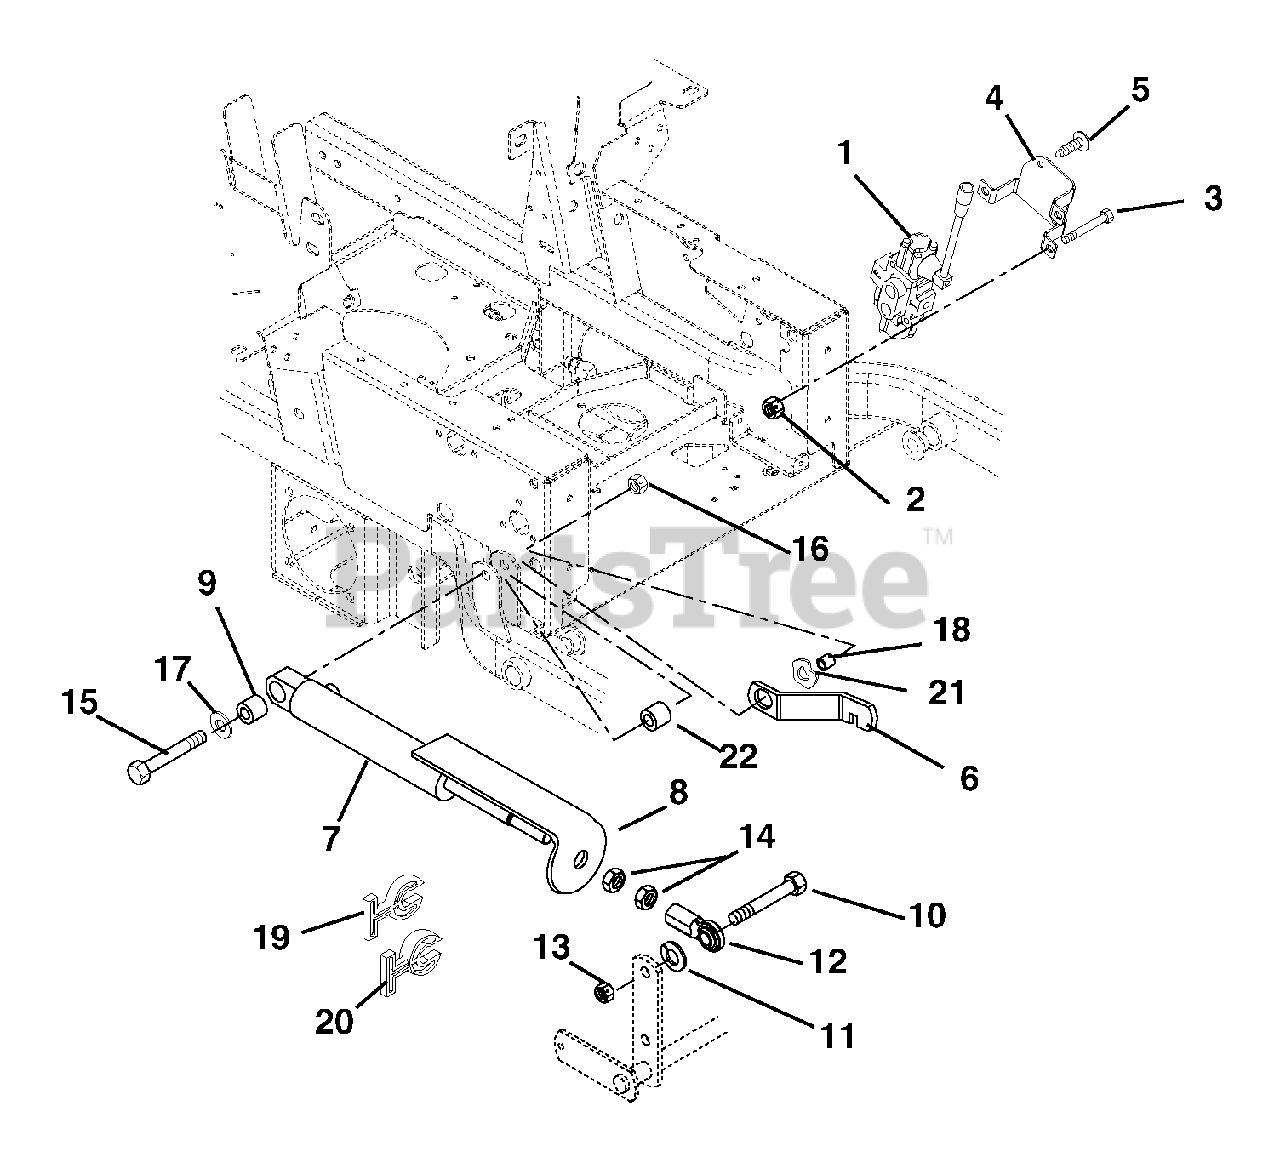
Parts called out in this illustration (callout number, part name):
1	Valve, Hydraulic
2	Nut, Locking Top Flange .31-18
3	Bolt, Hex .31-18 x 2.25 Grade 5
4	Valve Mounting Bracket
5	Screw, Tapping .38-16 x .50 Hex Washer Head
7	Cylinder, Hydraulic Lift
8	Strap, Cut Indicator/Guard
9	Bushing .516 x 1.000 x 1.050
10	Bolt, Hex .62-11 x 2.25 Grade 8
11	Washer, Lock .62 x .156
12	Rod End - Female - Right Hand .63
13	Nut, Locking Center .62-11
14	Nut, Jam .625-18
15	Post, Cylinder Stop
16	Nut, Locking Top Flange .50-13
17	Washer, Flat Steel .515 x 1.625 x .25
18	Bushing, Flange .515 x .75 x .275 x 1.12
19	Stop, Cylinder .34 Thick
20	Stop, Cylinder .68 Thick
21	Washer, Wave .076 x 1.12 xz .08
22	Spacer .50 I.D. x .88 O.D. x .88
